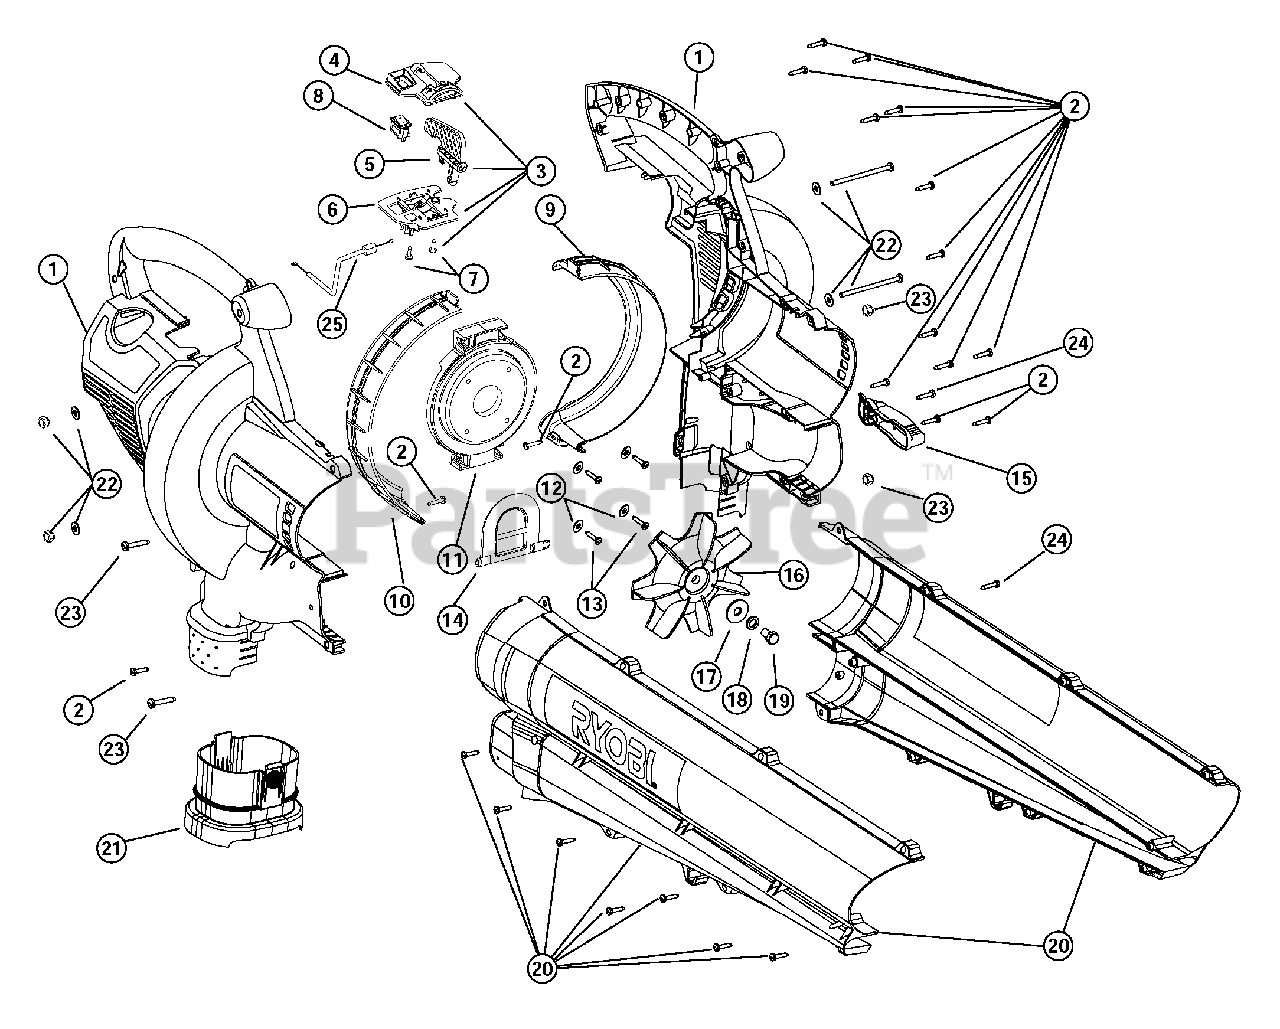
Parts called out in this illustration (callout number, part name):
1	Engine Cover Assembly
2	Cover Screw
3	Throttle Control Assembly
4	Upper Throttle Control Plate
5	Throttle Control Lever
6	Lower Throttle Control Plate
7	Screw, Plastic
8	Rocker Switch Assembly
9	Left Side Liner
10	Right Side Liner
11	Engine Mounting Plate
14	Mode Control Flapper
15	Mode Control Lever
16	Impeller Blade
17	Washer
18	Lock Washer
20	Blower/Vac Tube Assembly
21	Vacumm Bag Adapter
22	Mounting Plate Hardware
23	Blower/Vac Tube Mounting Hardware
25	Throttle Cable
